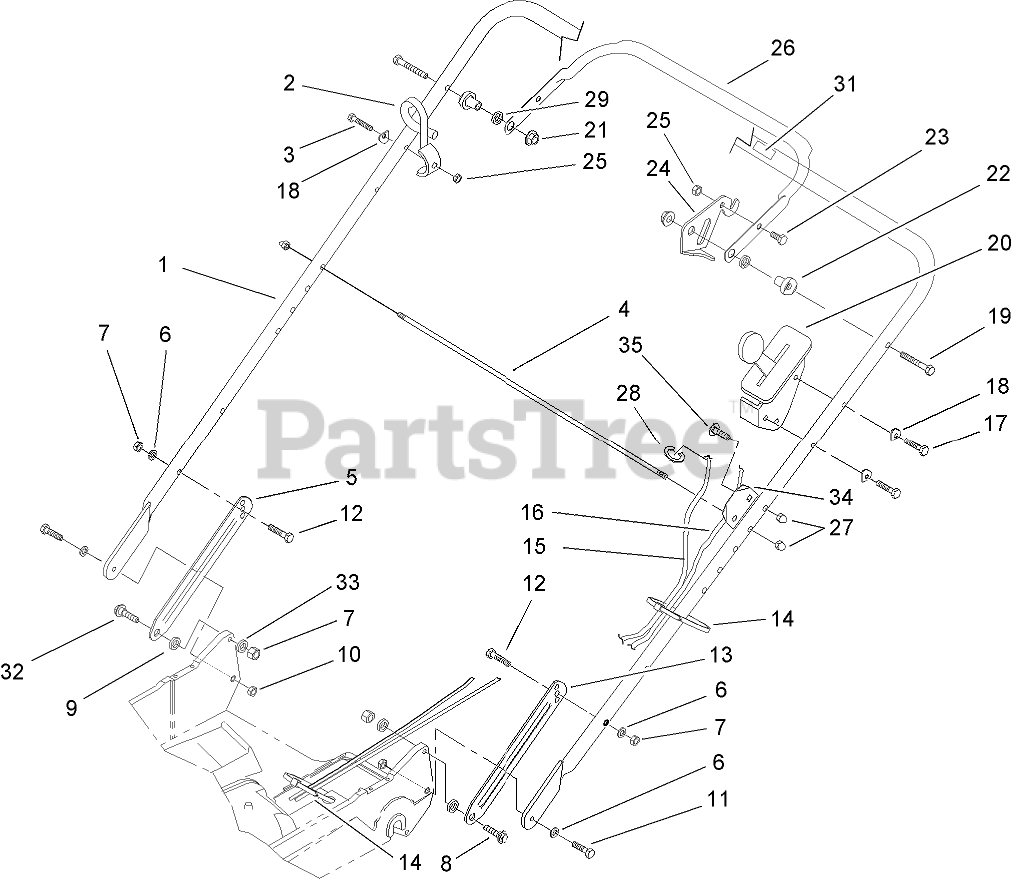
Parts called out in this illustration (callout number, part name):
2	GUIDE-ROPE
3	SCREW-HH
4	ROD-SUPPORT, BAG
5	LATCH-HANDLE, RH
6	WASHER-BELLEVILLE
7	NUT-LOCK, NI
8	SCREW-SHOULDER
9	SPACER
10	NUT-LOCK, NI
11	SCREW-HH
12	SCREW-HH
13	LATCH-HANDLE, LH
14	TIE-CABLE
15	Cable-Brake
16	THROTTLE CABLE ASM
17	SCREW-HH
18	WASHER
19	SCREW-HH
20	CONTROL-THROTTLE
21	NUT-LOCK, NI
22	SPACER-SUPPORT
23	SCREW-HH
24	LEVER-CONTROL
25	NUT-LOCK, NI
26	BAR-CONTROL
27	NUT-CAP
28	E-RING
29	SPACER-NYLON
31	DECAL-PROTECTION, EAR
32	SCREW-SHOULDER
33	WASHER-PLAIN
34	PLATE-ALIGNING, BAG
35	SCREW-CARR
99	GRASS BAG ASM
